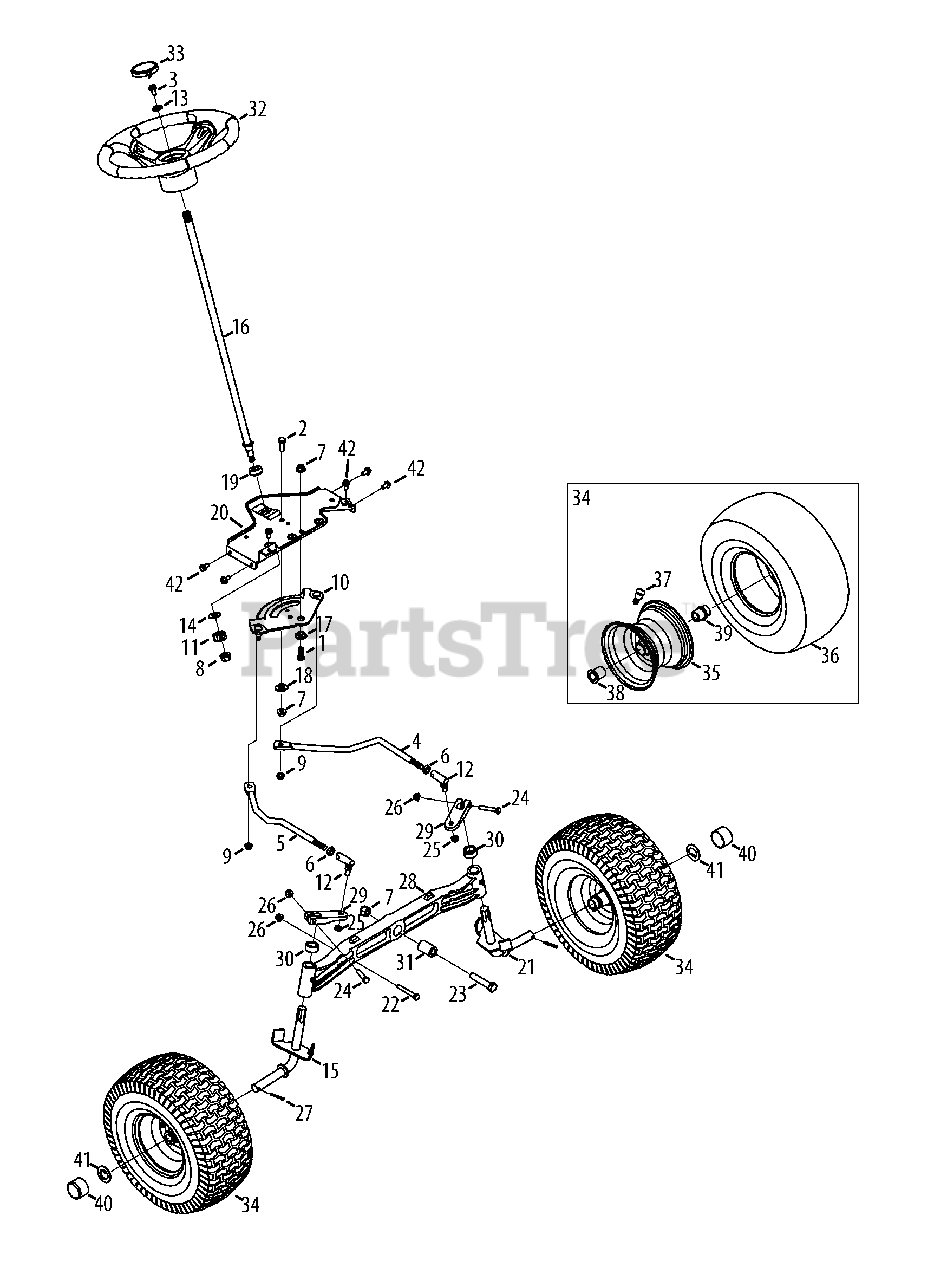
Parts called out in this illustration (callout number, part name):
1	Hex Head Screw, 3/8-16:1.00
2	Hex Head Screw, 3/8-16:1.00
3	Hex Head Screw, 5/16-18:1.00
4	LH Drag Link
5	RH Drag Link
6	Jam Nut, 7/16-20
7	Flangelock Nut, 3/8-16
8	Flangelock Nut, 7/16-20
9	Flangelock Nut, 5/16-18
10	Steering Gear
11	Steering Pinion Gear
12	Ball Joint, 7/16-20
13	Flat Washer, .406 x .875 x .105
14	Flat Washer, .51 x 1.12 x .06
15	RH Axle Assembly
16	Steering Shaft, .625 OD x 24.25 LG
17	Shoulder Spacer, .385 x 1.25 x .3025
18	Spacer, .38 x 1.375
19	Hex Flange Bearing 5/8 PM
20	Steering Support Bracket
21	LH Axle Assembly
22	Hex Head Screw, 5/16-18:2.25
23	Hex Head Screw, 3/8-16:2.50
24	Hex Head Screw, 5/16-18:1.75
25	Hexlock Nut, 3/8-24
26	Flangelock Nut, 5/16-18
27	Cotter Pin, 5/32:1.25
28	Pivot Bar Axle
29	Steering, Block
30	Spacer, .71 ID x .125 OD x .56LG
31	Spacer, .385 x 1.00 x 1.5075
32	Steering Wheel, Standard Grip
33	Steering Wheel Cap, Sprig
34	Wheel Assembly
35	Rim Assembly
37	Tubeless Air Valve
38	Flange Bearing, .760 x 1.00 x 1.20LG
39	Flange Bearing, .760ID
40	Bumper Cap
41	Flat Washer, .781ID x 1.590OD
42	Screw, Self-tapping, 5/16-18, .750,
